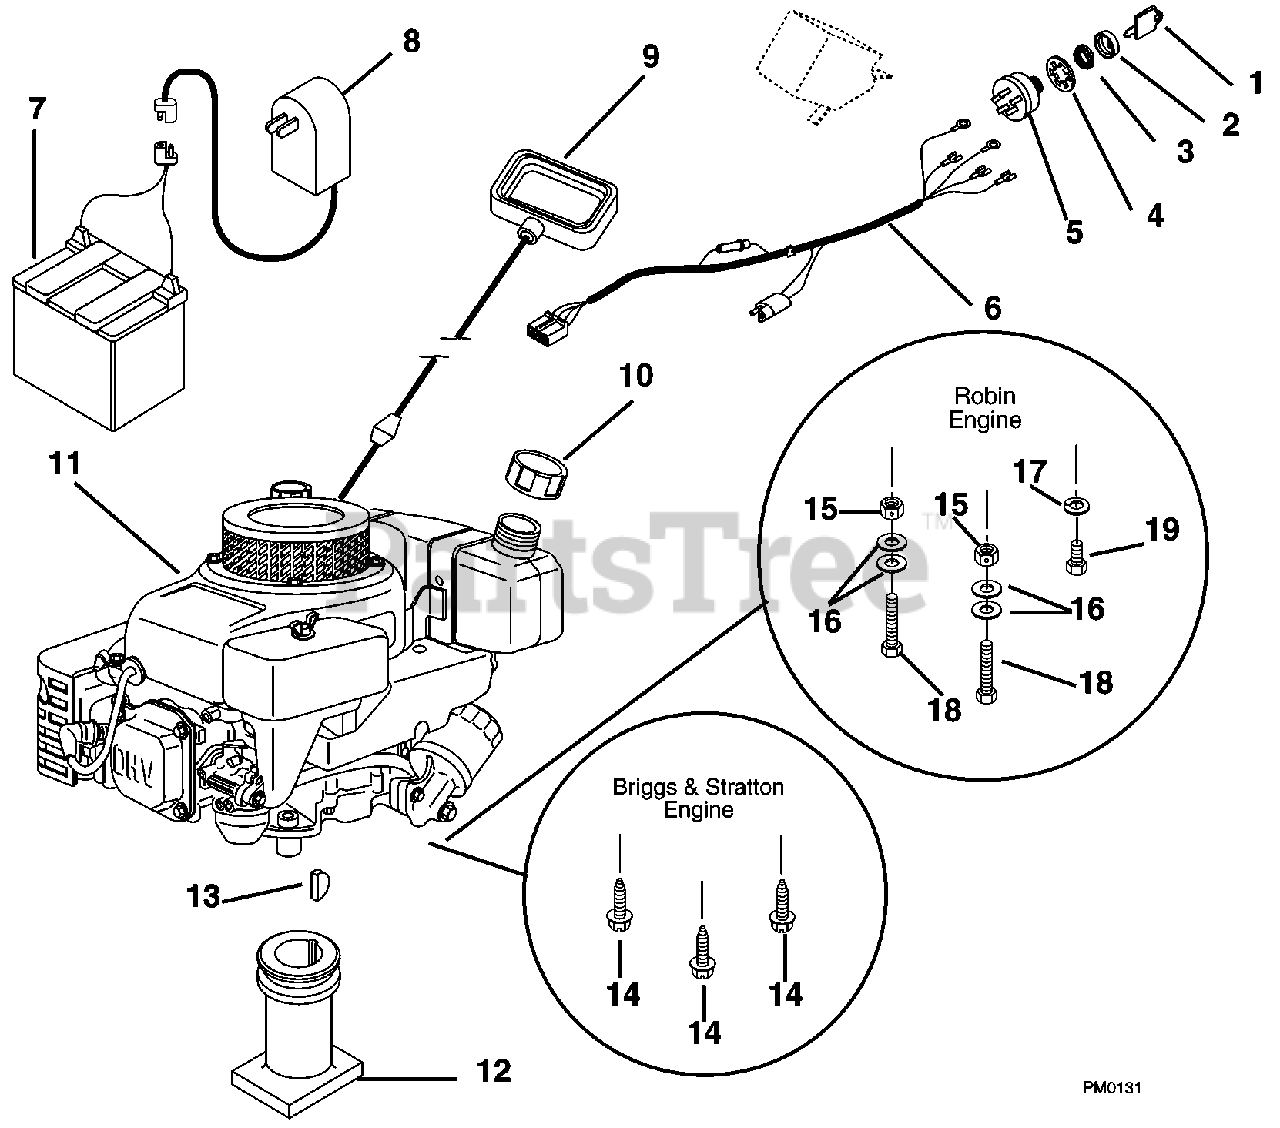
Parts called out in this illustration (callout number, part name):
1	Key w/Cap (580 RSE)
2	Cap-Ignition Switch (580 RSE)
3	Nut, Panel .625-32 (580 RSE)
4	Washer-Locking Internal .625 x .045 (580 RSE)
5	Key Switch (580 RSE)
6	Wire Harness (580 RSE)
7	Battery (580 RSE)
8	Battery Charger (580 RSE)
9	Recoil Start Handle
11	Engine, Robin 6 HP 4 Cycle (600 C)
12	Blade Adapter .875 Dia w/Keyway (580 RS, RSE, RSW)
13	Key-Woodruff .156 x .625 x .25
14	Screw-Tapping .38-16 x 1.00 Hex Washer Head
15	Nut-Locking-Center .31-18 (600 C)
16	Washer-Flat-Steel .312 x .734 x .065 (600 C)
17	Washer-Locking .312 x .097 Heavy
18	Bolt-Hex .31-18 x 1.25 Grade 5 (600 C)
19	Bolt-Hex .31-18 x .75 Grade 5 (600 C)
